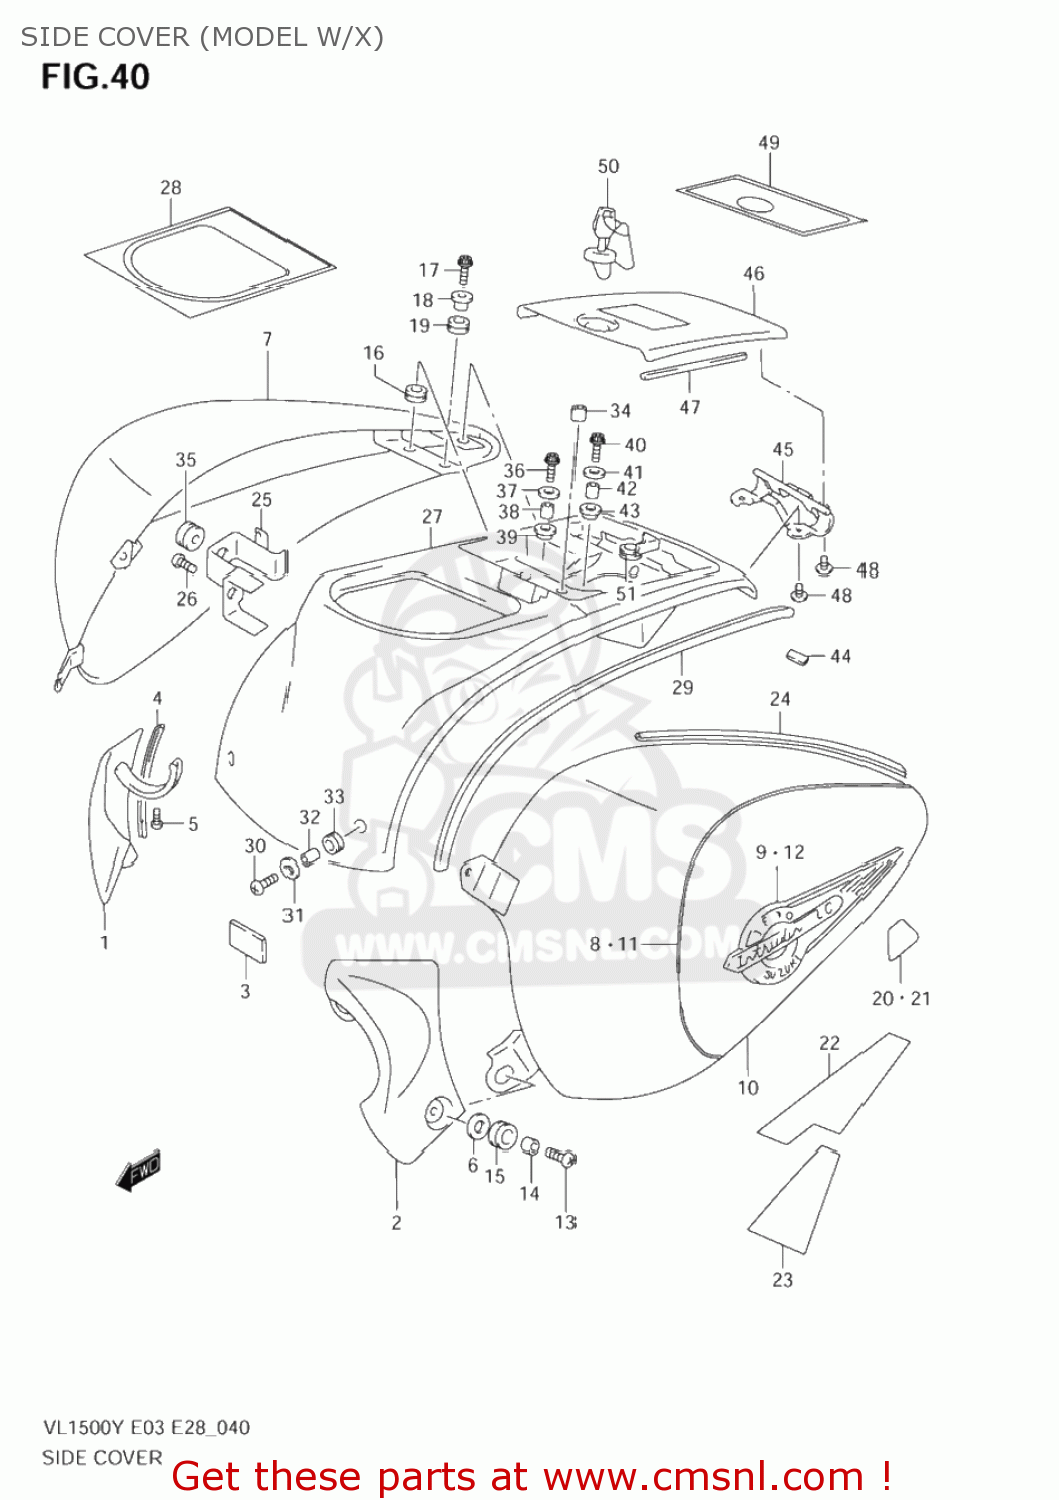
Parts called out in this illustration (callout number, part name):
1	COVER COMP,FRAME HEAD
2	COVER COMP,FRAME HEAD
3	CUSHION,METER COVER RE
4	MOLDING,FRAME HEAD COVER
5	SCREW(6X20)
6	WASHER
7	COVER ASSY,SIDE UPR,R
8	TAPE,SIDE COVER UPR,R
9	EMBLEM,TANK COVER,R
10	COVER ASSY,SIDE UPR,L
11	TAPE,SIDE COVER,UPPER
12	EMBLEM,TANK COVER,L
13	SCREW(6X16)
14	SPACER(6.5X9X7.2)
15	CUSHION
16	CUSHION,SIDE UP METER & FRAME
17	BOLT
18	WASHER,SIDE UPR COVER
19	CUSHION,SIDE UPR COVER
20	TAPE,SIDE COVER UPR,R
21	TAPE,SIDE COVER UPR,L
22	CUSHION,SIDE UPR COVER,R
23	CUSHION,SIDE UPR COVER,R
24	MOLDING,SIDE UPPER COVER
25	BRACKET,SIDE UPPER COVER
26	BOLT
27	COVER,METER & FUEL INLET
28	TAPE,METER COVER
29	MOLDING,METER COVER
30	SCREW(6X16)
31	WASHER(6.5X18X1.5)
32	SPACER(6.5X9X5.7)
33	CUSHION
34	CUSHION
35	CUSHION
36	BOLT,OIL PAN
37	WASHER(6.5X18X1.6)
38	SPACER(6.5X9X11)
39	CUSHION,METER COVER
40	BOLT MAGNETO S
41	WASHER(6.5X18X1.6)
42	SPACER(6.5X9X5.7)
43	CUSHION
44	CUSHION,METER COVER RE
45	HINGE COMP,FUEL LID
46	LID,FUEL INLET
47	CUSHION,FUEL LID
48	SCREW 6X12
49	TAPE,FUEL LID
50	LOCK SET,COVER
51	CUSHION,RR,L
